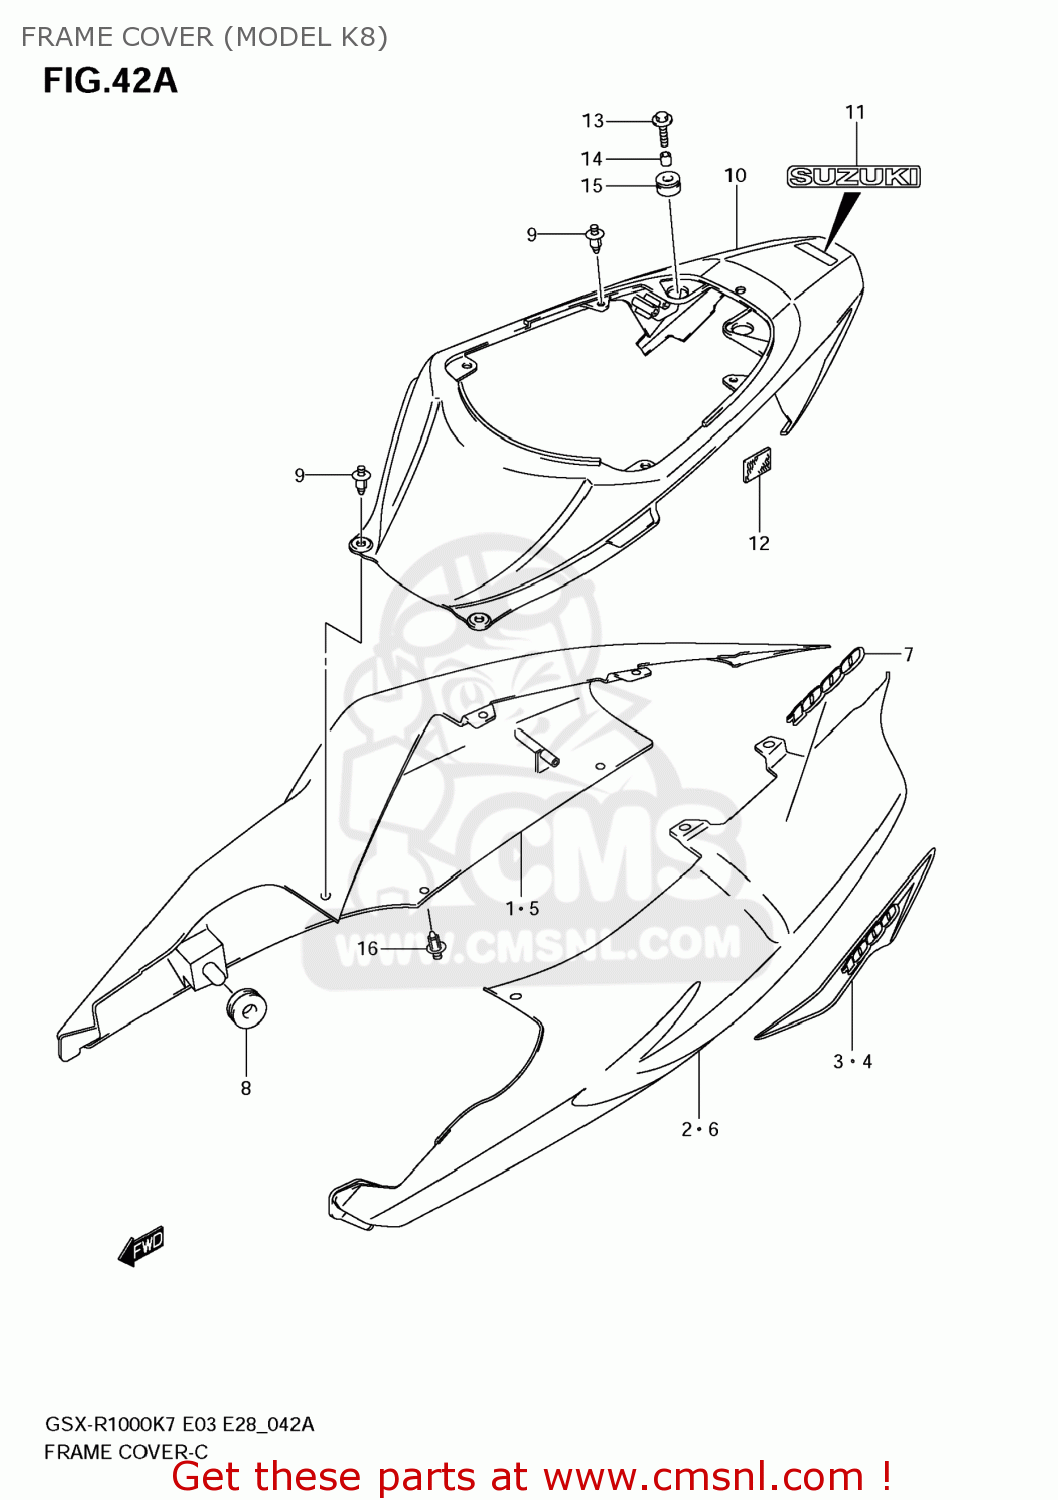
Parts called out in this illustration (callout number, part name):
1	COVER,FRAME,R(WHITE)
2	COVER,FRAME,L(WHITE)
3	TAPE,FRAME COVER,R
4	TAPE,FRAME COVER,L
5	COVER,FRAME,R(GOLD)
6	COVER,FRAME,L(GOLD)
7	EMBLEM,1000
8	CUSHION
9	CLIP(BLACK)
10	COVER,FRAME CTR
11	EMBLEM,SUZUKI
12	FASTENER
13	BOLT(6X30)
14	SPACER(6.5X10X15)
15	CUSHION
16	CLIP(BLACK)
